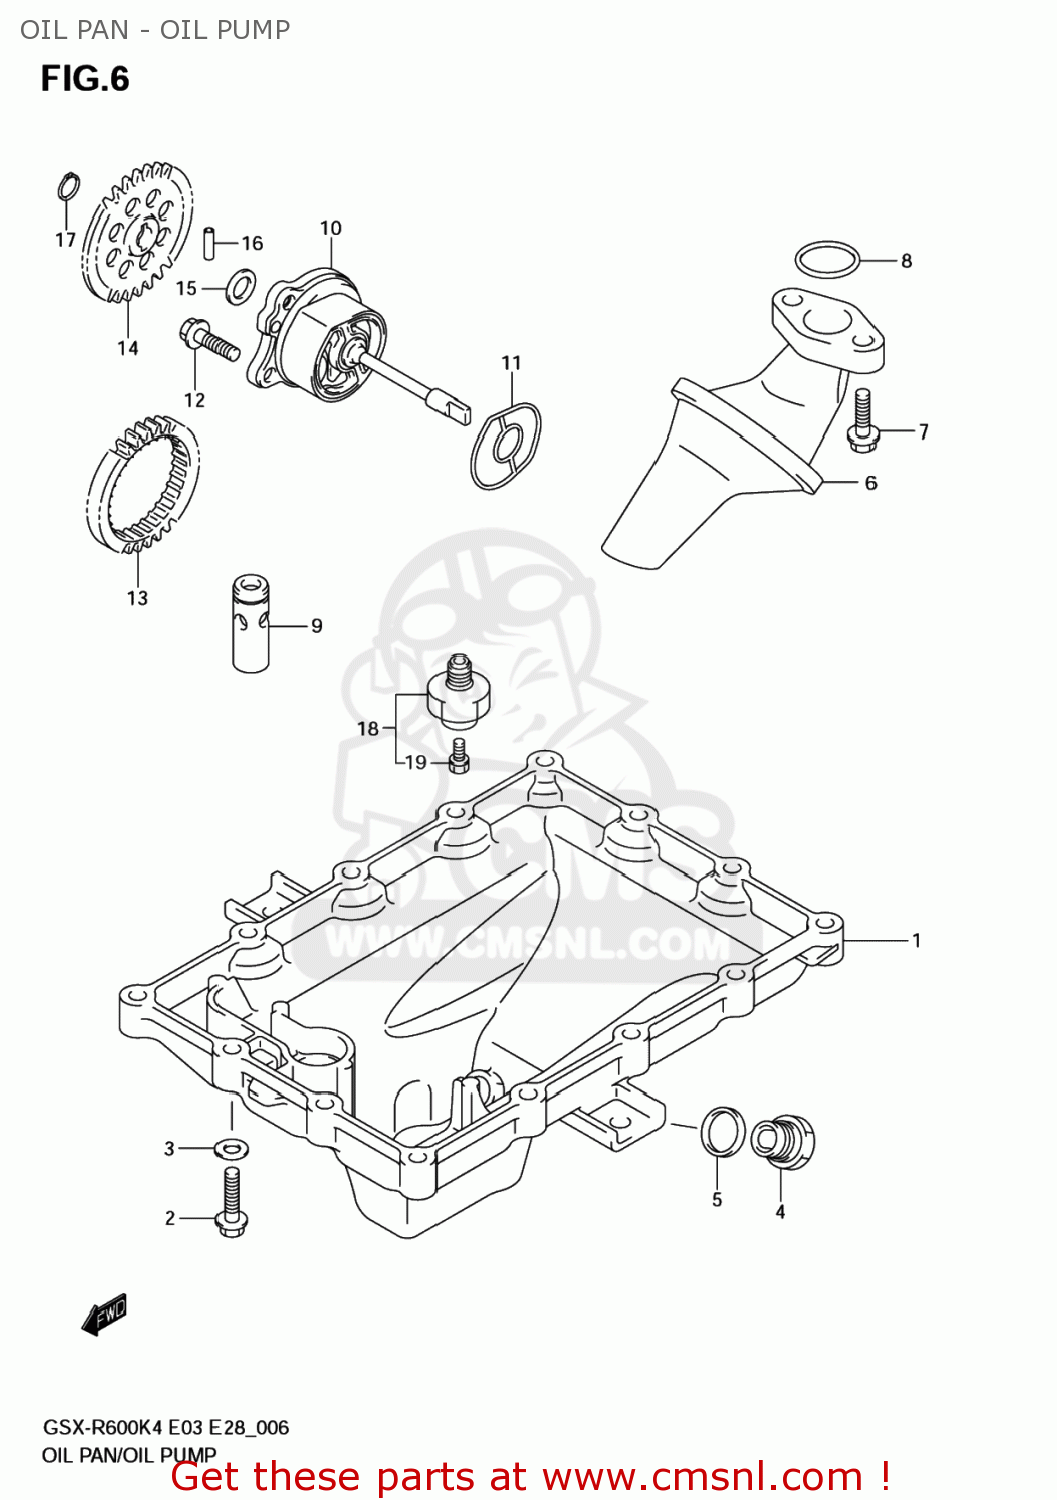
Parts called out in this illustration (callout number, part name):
1	PAN,OIL
2	SCREW
3	GASKET(5.8X13X1.2) (NAS)
4	PLUG(14X20)
5	GASKET(13.8X18.8X4.8) (NAS)
6	STRAINER ASSY,ENGINE OIL
7	BOLT
8	O RING(D:2.62,ID:20.3)
9	VALVE ASSY,OIL RELIEF(7K)
10	PUMP ASSY,ENGINE OIL
11	O RING,OIL PUMP
12	SCREW
13	GEAR,OIL PUMP DRIVE
14	GEAR,OIL PUMP DRIVEN
15	SHIM(10X18X0.5)
16	PIN(4X15.8)
17	CIRCLIP,10MM
18	SWITCH ASSY,OIL PRESSURE
19	BOLT,OIL PRESSURE SWITCH
